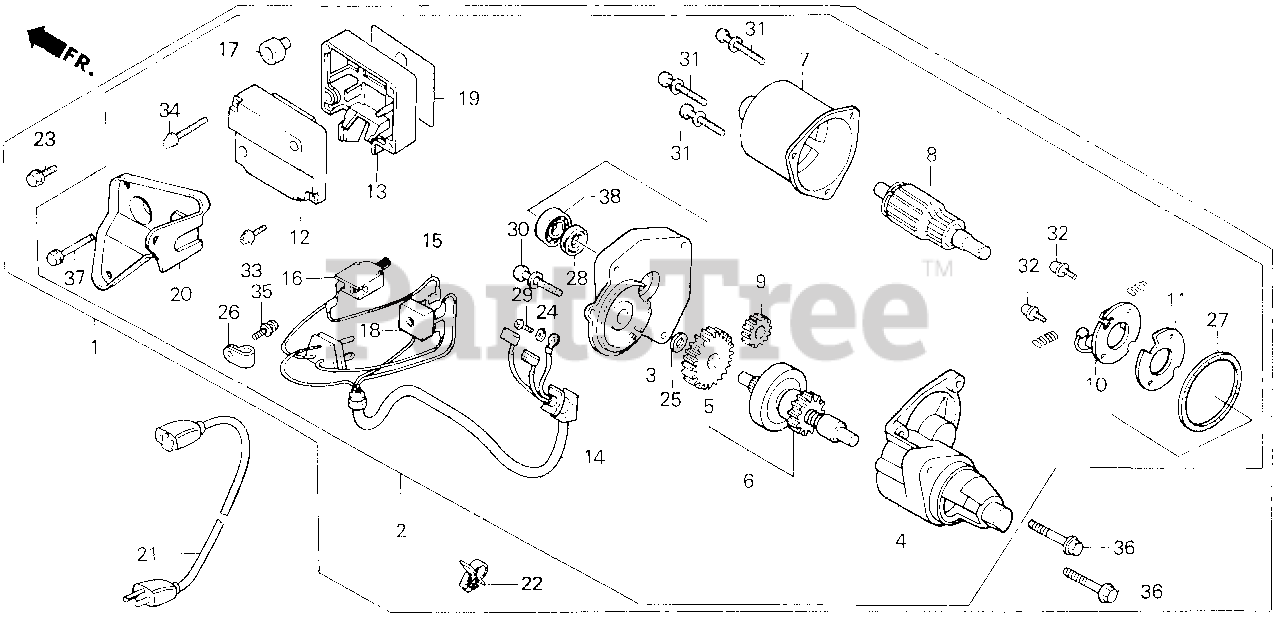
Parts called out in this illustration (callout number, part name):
1	STARTER KIT, SELF (A.C.) Use up to Engine SN 1171448.
2	MOTOR ASSY., STARTER (A.C.) Use up to Engine SN 1171448.
3	HOUSING, CENTER Use up to Engine SN 1171448.
4	HOUSING, PINION Use up to Engine SN 1171448.
5	GEAR, REDUCTION Use up to Engine SN 1171448.
6	CLUTCH, OVERRUNNING Use up to Engine SN 1171448.
7	YOKE Use up to Engine SN 1171448.
8	ARMATURE Use up to Engine SN 1171448.
9	GEAR, DRIVE Use up to Engine SN 1171448.
10	HOLDER ASSY., BRUSH Use up to Engine SN 1171448.
11	SHEET, HOLDER Use up to Engine SN 1171448.
12	COVER Use up to Engine SN 1171448.
13	CASE Use up to Engine SN 1171448.
14	WIRE Use up to Engine SN 1171448.
15	SUB-WIRE Use up to Engine SN 1171448.
16	SWITCH, STARTER Use up to Engine SN 1171448.
17	CAP Use up to Engine SN 1171448.
18	DIODE Use up to Engine SN 1171448.
19	PLATE, CAUTION Use up to Engine SN 1171448.
20	BRACKET, SWITCH BOX Use up to Engine SN 1171448.
21	WIRE, POWER Use up to Engine SN 1171448.
22	HOLDER, STOP SWITCH WIRE Use up to Engine SN 1171448.
23	BOLT, FLANGE (6X12) (CT200) Use up to Engine SN 1171448.
24	WASHER, STAR (4MM) Use up to Engine SN 1171448.
25	WASHER Use up to Engine SN 1171448.
26	CLIP, CORD (5/16) Use up to Engine SN 1171448.
27	GASKET Use up to Engine SN 1171448.
28	OIL SEAL Use up to Engine SN 1171448.
29	SCREW, PAN (4X6) Use up to Engine SN 1171448.
30	SCREW-WASHER (5X16) Use up to Engine SN 1171448.
31	SCREW-WASHER (5X30) Use up to Engine SN 1171448.
32	SCREW-WASHER (4X12) Use up to Engine SN 1171448.
33	SCREW-WASHER (4X25) Use up to Engine SN 1171448.
34	SCREW-WASHER (4X30) Use up to Engine SN 1171448.
35	SCREW-WASHER (5X16) Use up to Engine SN 1171448.
36	BOLT, FLANGE (8X40) Use up to Engine SN 1171448.
37	BOLT, FLANGE (6X40) Use up to Engine SN 1171448.
38	BEARING, RADIAL BALL Use up to Engine SN 1171448.
